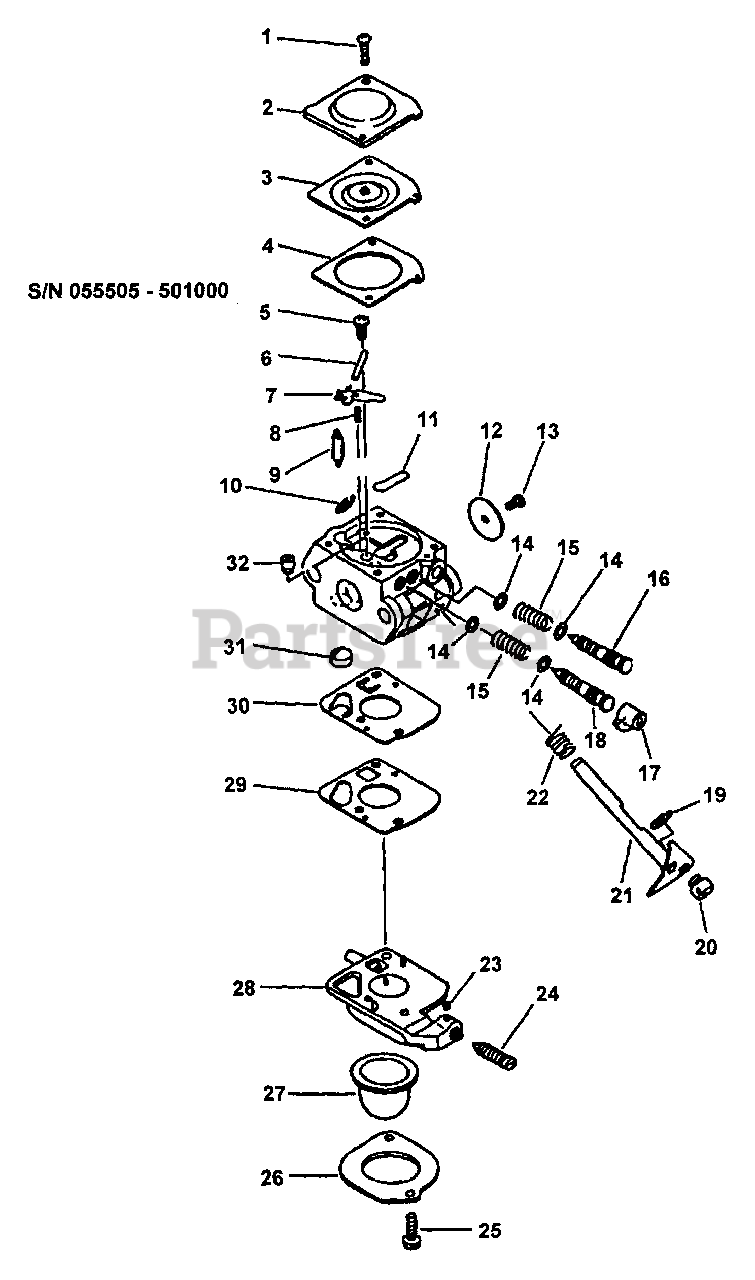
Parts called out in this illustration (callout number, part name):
2	COVER, METERING
3	DIAPHRAGM, METERING
4	GASKET, METERING
5	SCREW, METERING LEVER PIN
6	PIN, METERING LEVER
7	LEVER, METERING
8	SPRING, METERING LEVER
9	VALVE, NEEDLE
10	RING, RETAINING
11	PLUG, WELCH
12	VALVE, THROTTLE
16	NEEDLE - LOW SPEED
17	CAP, LIMITER
18	NEEDLE - HIGH SPEED
19	RING, RETAINING
21	SHAFT, THROTTLE
22	SPRING, RETURN
23	PIECE, FRICTION
24	SCREW, IDLE ADJUST
25	SCREW, RETAINER
26	RETAINER, PURGE BULB
27	BULB, PURGE
28	BASE, PURGE
29	GASKET, PURGE
30	DIAPHRAGM, PURGE
31	STRAINER
32	NOZZLE, CHECK VALVE
